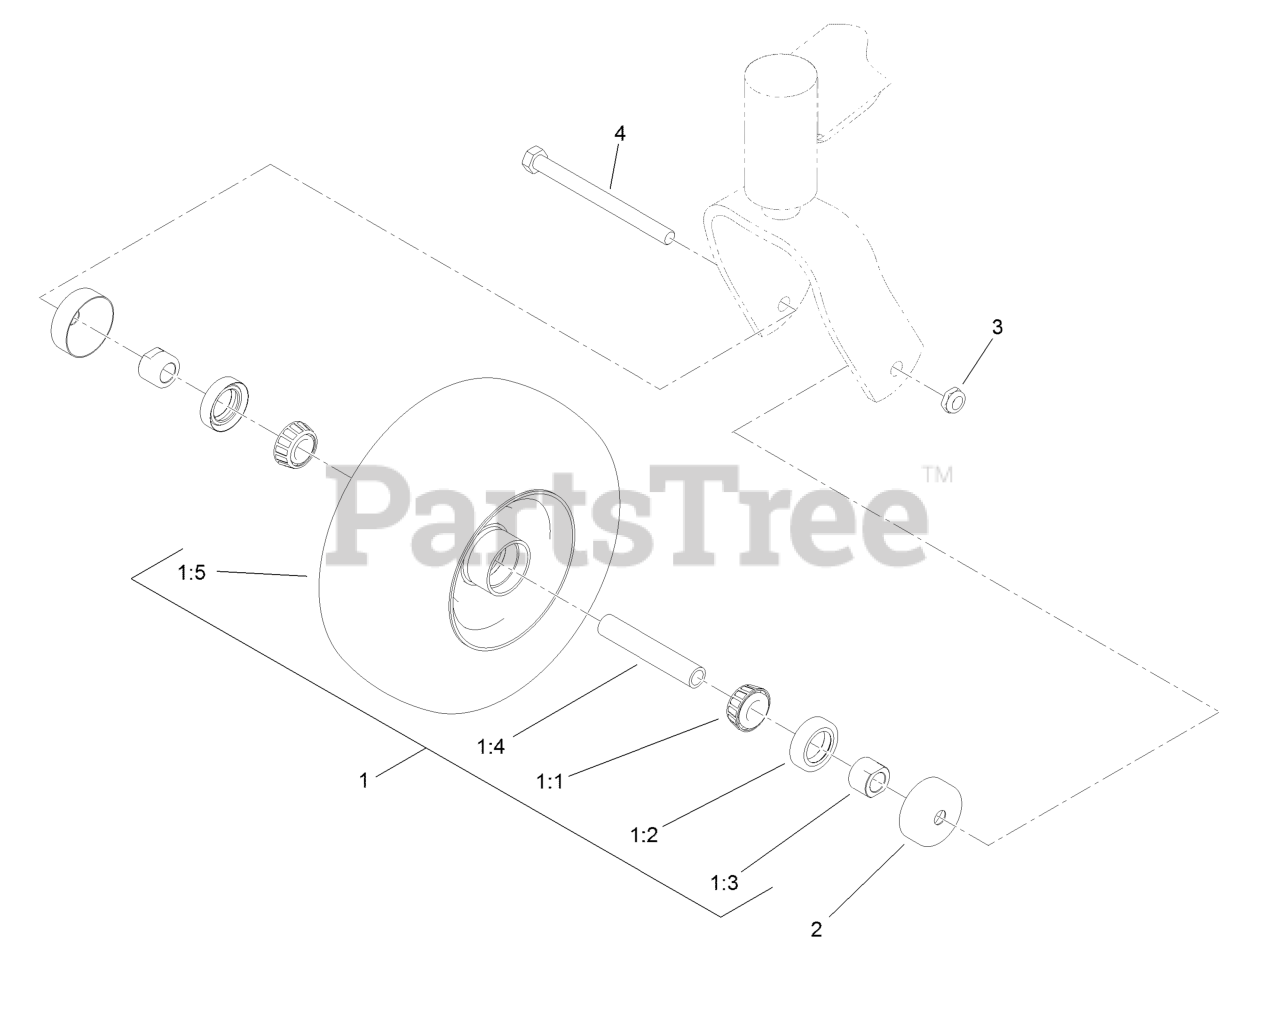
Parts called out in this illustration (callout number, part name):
1	Wheel And Bearing ASM
1:1	Bearing-Cone Tapered Roller
1:2	Seal-Double Lip
1:3	Spacer-Nut
1:4	Caster Axle ASM
1:5	Wheel And Tire ASM
2	Guard-Seal
3	Nut-Nyloc 1/2-13 Thin
4	Screw-HH 1/2-13 X 6
